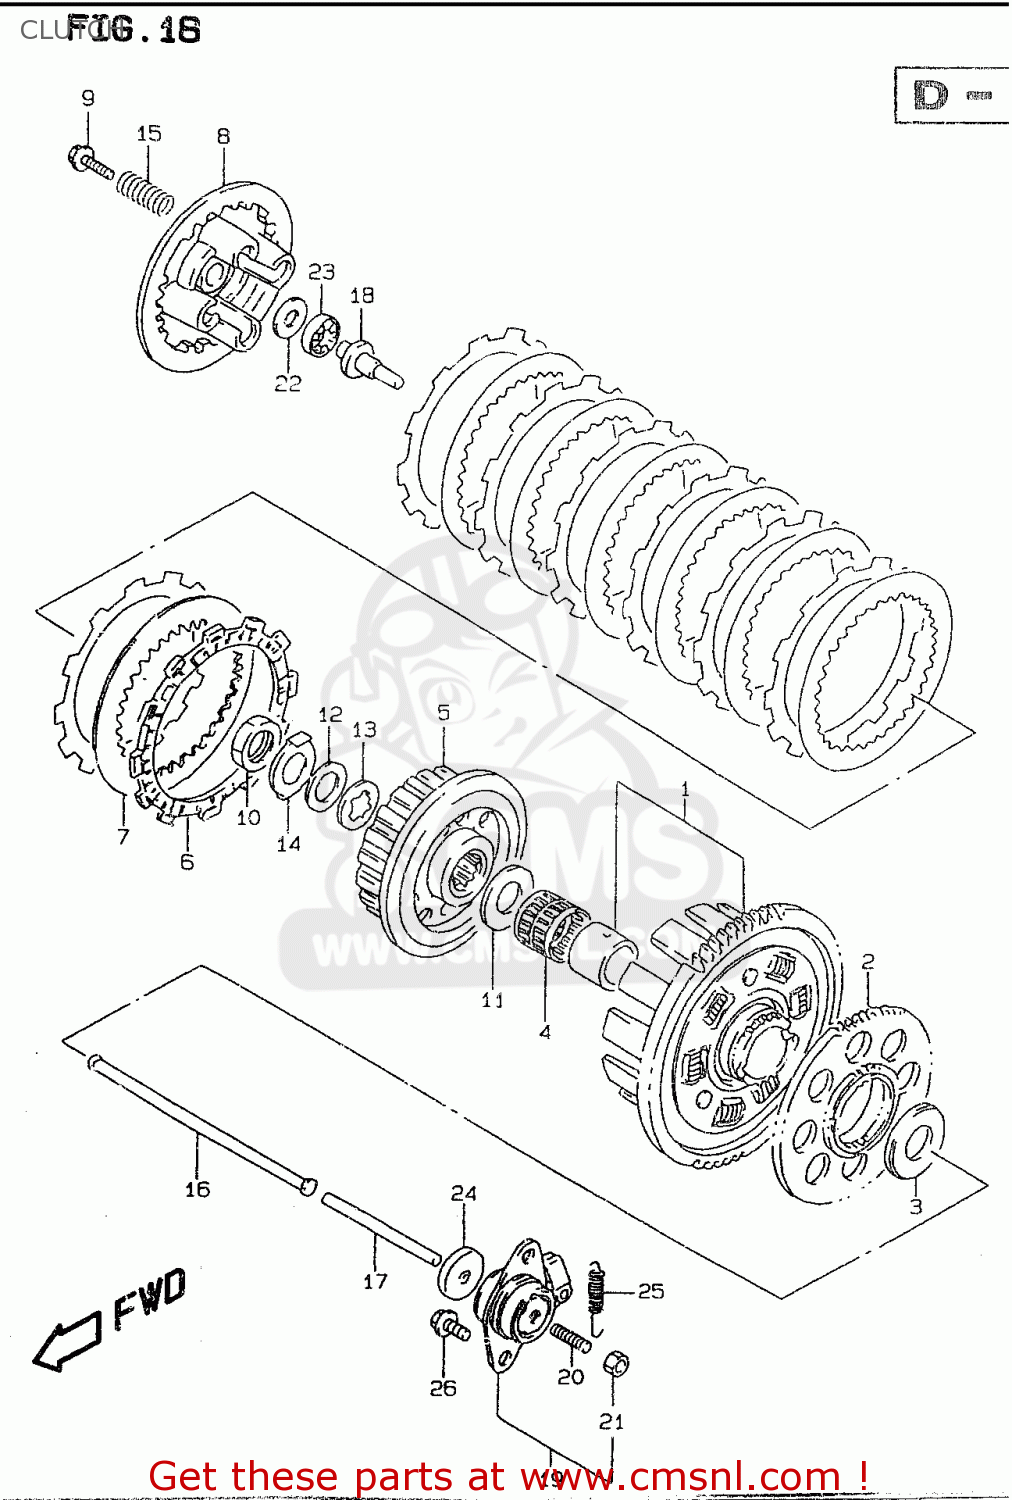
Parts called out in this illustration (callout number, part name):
1	GEAR ASSEMBLY,PRIMARY DRIVE
2	GEAR,GENERATOR DRIVE
3	WASHER(25X54X2.5)
4	BEARING(35X40X35.8)
5	HUB,CLUTCH SLEEVE
6	PLATE,CLUTCH DRIVE (NAS)
7	PLATE,CLUTCH DRIVEN (NAS)
8	DISC,CLUTCH PRESSURE
9	BOLT(6X16)
10	NUT
11	WASHER(25X50X2.5)
12	WASHER
13	WASHER,LOCK
14	WASHER
15	SPRING
16	ROD,CLUTCH PUSH,R
17	ROD,CLUTCH PUSH,L
18	PIECE,CLUTCH PUSH
19	SCREW ASSY,CLUTCH RELEASE
20	SCREW(6X25)
21	NUT
22	WASHER(15.5X28X1)
23	BEARING(15X28X2)
24	SEAL,OIL(6X34X5.5)
25	SPRING
26	BOLT
